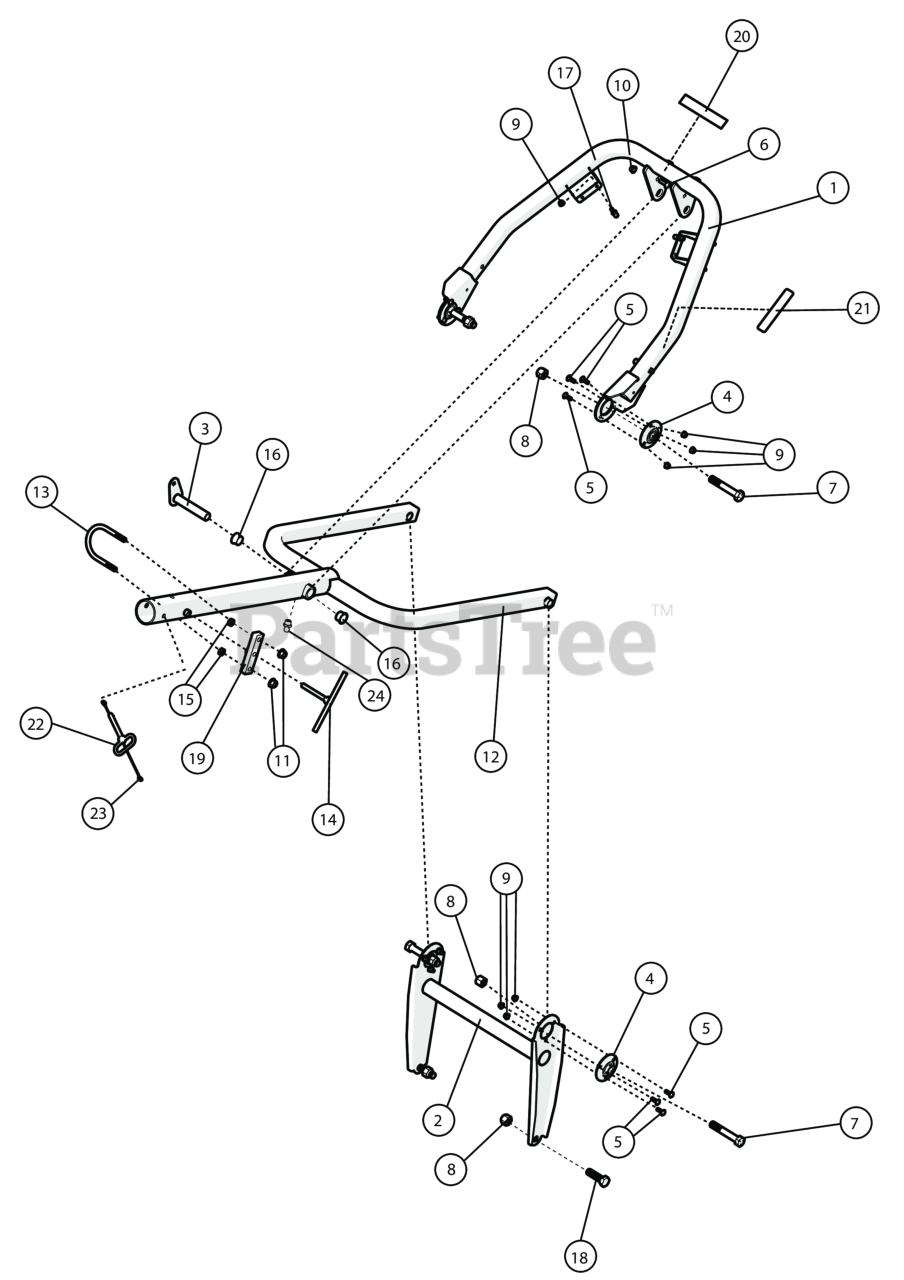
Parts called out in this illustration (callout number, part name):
1	WA, ARM, UPPER
2	WA, ARM, OSCILLATOR
3	PIVOT, ARTICULATING ARM
4	BEARING AND FLANGETTE ASSY .75"
5	BOLT CARRIAGE 5/16"-18 X 1" ZP
6	BOLT CARRIAGE 3/8"-16 X 1 1/4" ZP
7	SCR-CAP, HEX, 3/4-10 X 4.500" ZP
8	NUT LOCK 3/4" - 10 ZP
9	NUT-HEX-NYLK, FLG .3125-18 ZP
10	NUT-HEX-NYLK, FLG .375"-16 ZP
11	NUT-HEX-NYLK, FLG .500"-13 ZP
12	WA, ARM, DRILL
13	U-BOLT, 1/2" X 4" X 5" ZP
14	T-HANDLE CLAMP
15	NUT LOCK 1/2"-13 HVY ZP
16	BUSHING, 1.00" ID
17	BALL STUD, 1/2" X 5/16-18 ZP
18	SCREWCAP 3/4-10 X 2 1/2" LG Z/P GR 5
19	WA, CLAMP LOCK
20	LABEL, SAFETY MEN
21	DECAL, TRANSPORT LOCK
22	PIN, QUICK-RELEASE, .50" X 3.00"
23	LANYARD, 12" COATED STEEL
24	ZERK FITTING GREASE
